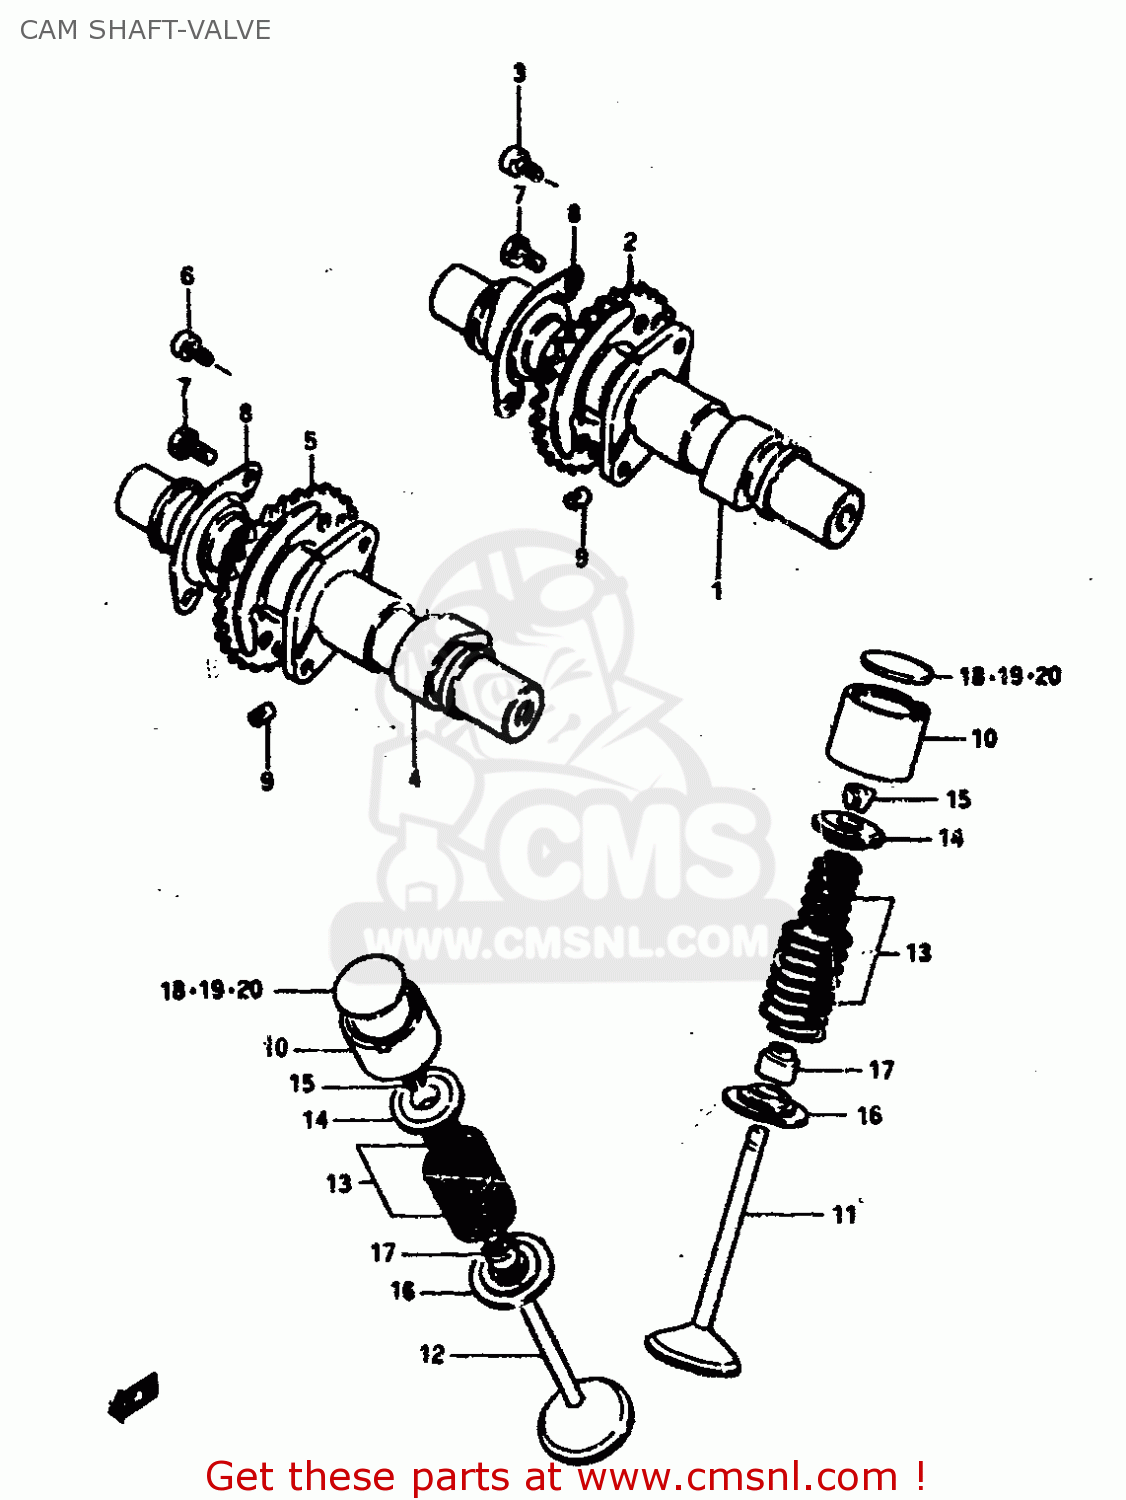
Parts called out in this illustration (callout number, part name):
1	CAMSHAFT
2	SPROCKET,CAMSHAFT
3	BOLT 6X11
4	CAMSHAFT,EXHAUST
5	SPROCKET,EXHAUST CAM(NT:30)
6	BOLT 6X11
7	BOLT(6X12.5)
8	WASHER,CAM CHAIN SPROCKET
9	PIN,SPROCKET
10	TAPPET
11	VALVE,INTAKE
12	VALVE,EXHAUST
13	SPRING SET,VALVE
14	RETAINER,VALVE SPRING
15	SHIM,TAPPET
16	SEAT,VALVE SPRING
17	SEAL,OIL(7X14.4X9)
18	SHIM,TAPPET
19	SHIM,TAPPET
20	SHIM,TAPPET
